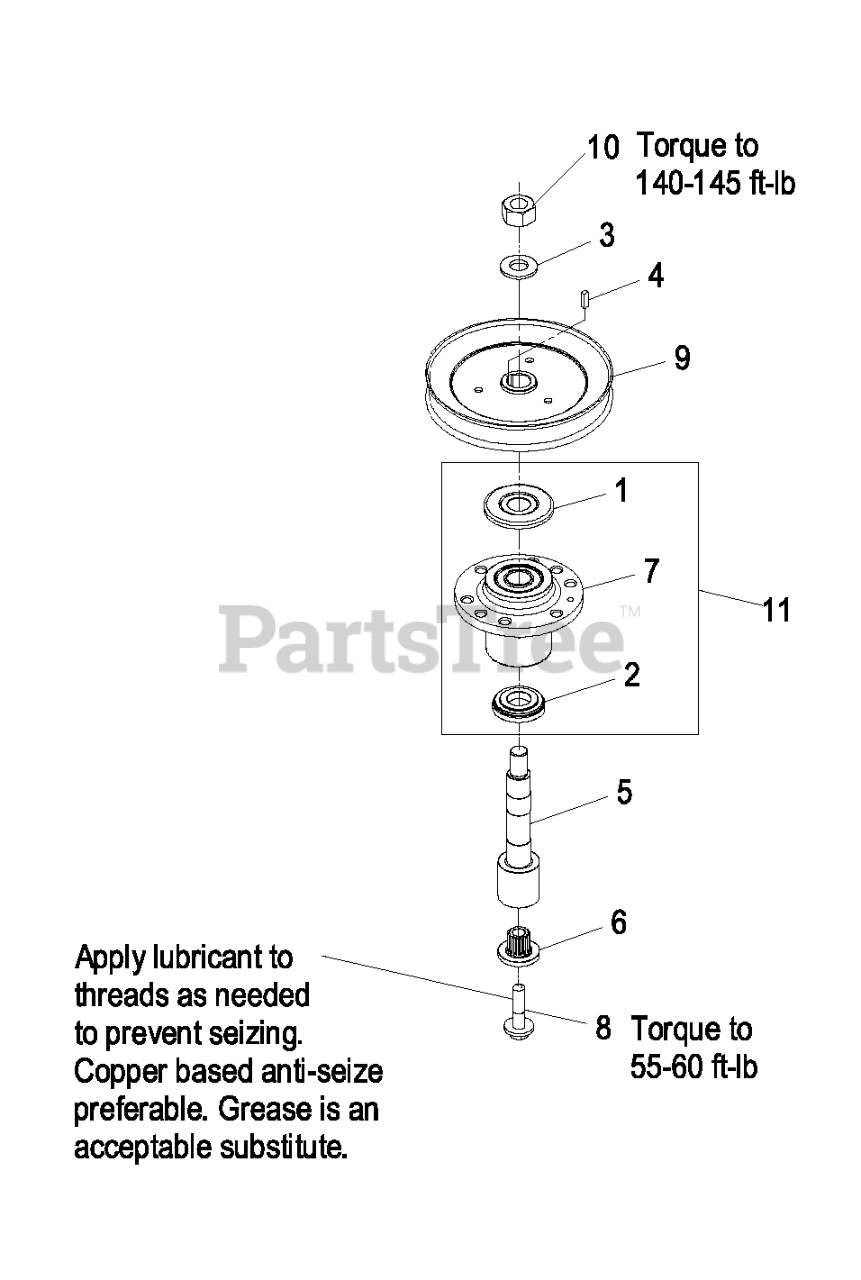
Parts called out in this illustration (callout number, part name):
1	GUARD-BEARING, TOP
2	SPACER-GUARD, BOTTOM
5	KIT, SPLINED SPINDLE 103-
6	BUSHING,SPLINED
8	SCREW,SEMS 1/2-20 X 2.19
9	SHEAVE,BLADE DRIVE 7.25
